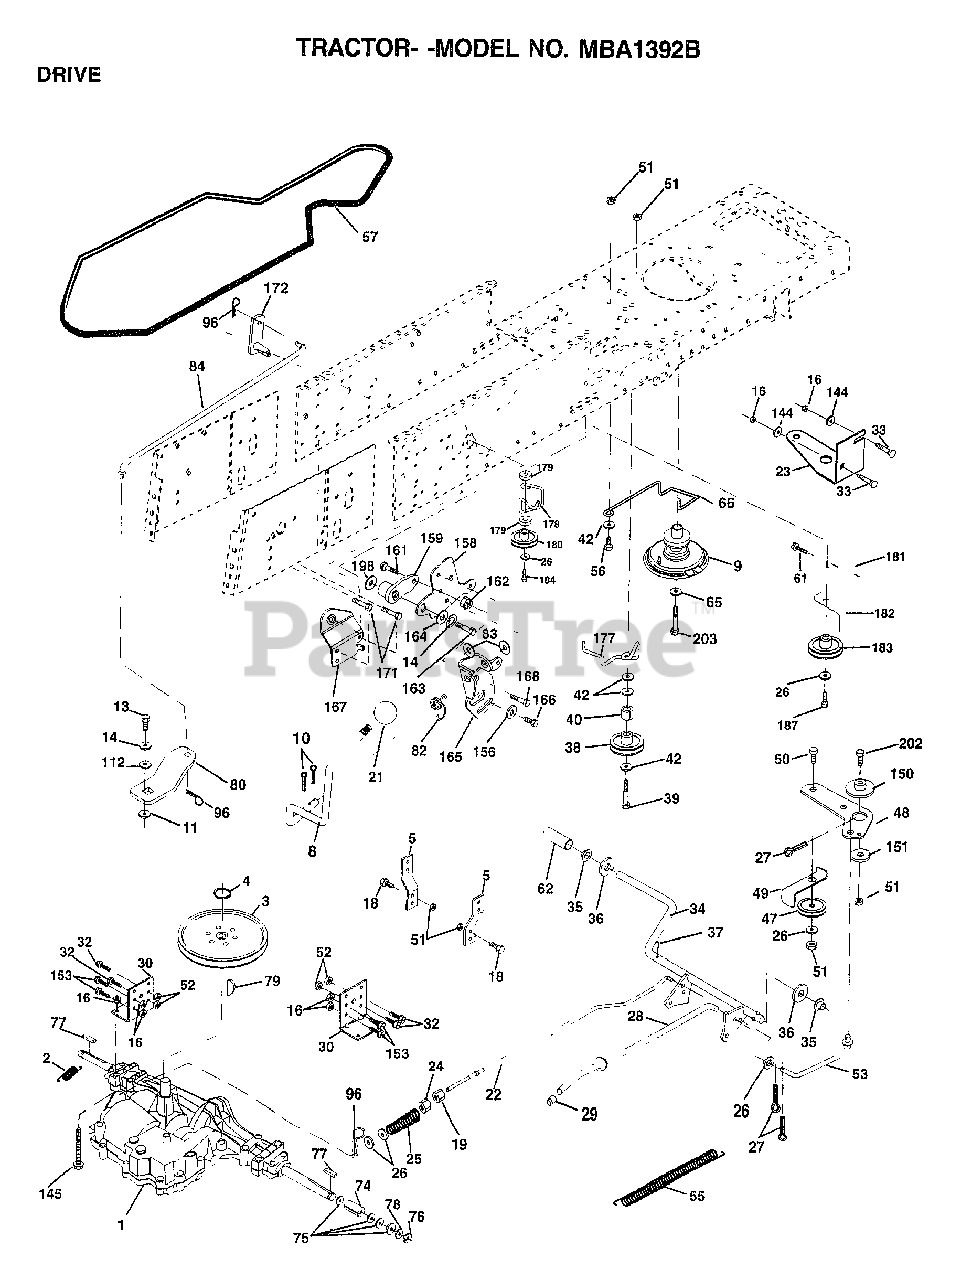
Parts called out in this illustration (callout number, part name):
2	SPRING.BRAKE.RETU
3	"PULLEY.TRANSAXLE.7"""
5	STRAP TORQUE
8	ROD.SHIFT.FENDER.ADJ.LT.CRD
9	CLUTCH ASM NORAM
10	PIN COTTER 1/8
11	WASH-SHFT PLT LT
13	BOLT.1/4-28.W/PAT
14	LOCKWASHER
16	NUT
18	BOLT
19	NUT
21	KNOB T (1/2-HOLE)
22	ROD.BRAKE.PMST.CRD
23	BRACKET CLUTCH
24	NUT
25	SPRING ROD LT
26	WASHER
27	COTTER PIN
28	ROD.BRAKE.PARK.LT
29	PLUNGER CAP T
30	TRANSAXLE MTG BKT
32	BOLT
33	BOLT
34	SHAFT.ASM.PEDAL.FOOT.CRD
35	NYLON BEARING
36	WASHER LT
38	PULLEY.FLAT
39	BOLT
40	SPACER T
42	WASHER
48	BELLCRANK.CLUTCH
49	RETAIN BELT
53	"LINK, CLUTCH T"
55	"SPRING, RETURN LT"
57	"V-BELT.KEV.111"""
61	SCREW
62	PEDAL COVER T
65	LOCKWASHER
66	KEEPER-BELT
74	SPACER AXLE
75	WASHER
76	E-RING LT
77	SQUARE KEY
78	WASHER
80	"ARM.SHIFT.20""TIRE"
82	"SPRING,TORSION"
83	WASHER
84	LINK.SHIFT.CRD
96	RETAINER M
112	WASHER LT
144	WASHER
145	BOLT.HEX.FLGHD
150	BUSHING.BELLCRANK.GRD.DR
151	WASHER
156	WASHER.SRRTD.5/16
158	BRKT.SHIFT.MOUNT
159	HUB.SHIFT
161	BOLT T
164	WASHER.5/8X.281X10GA
165	BRKT.PIVOT.LEVER
166	SCREW.5/16-18X5/8
167	BRKT.SUPT.SHIFT.CRD
168	BOLT.SHOULDER.5/16-18X.561
171	SCREW LT
172	SHAFT.ASM.SHIFT.FRT.CRD
177	KEEPOER.FLAT.IDLER
178	KEEPER.BELT.IDLER
179	WASHER
180	PULLEY.FLAT.IDLER
181	BRKT.IDLER.GRD.DR.CRD
182	"KEEPER.BELT.2.5"".OD.CRD"
183	PULLEY.V-IDLER
184	SCREW.HXWSH.3/8
187	SCREW
198	WASHER NYLINER
202	BOLT.3/8-16X1.50
203	BOLT HEX
